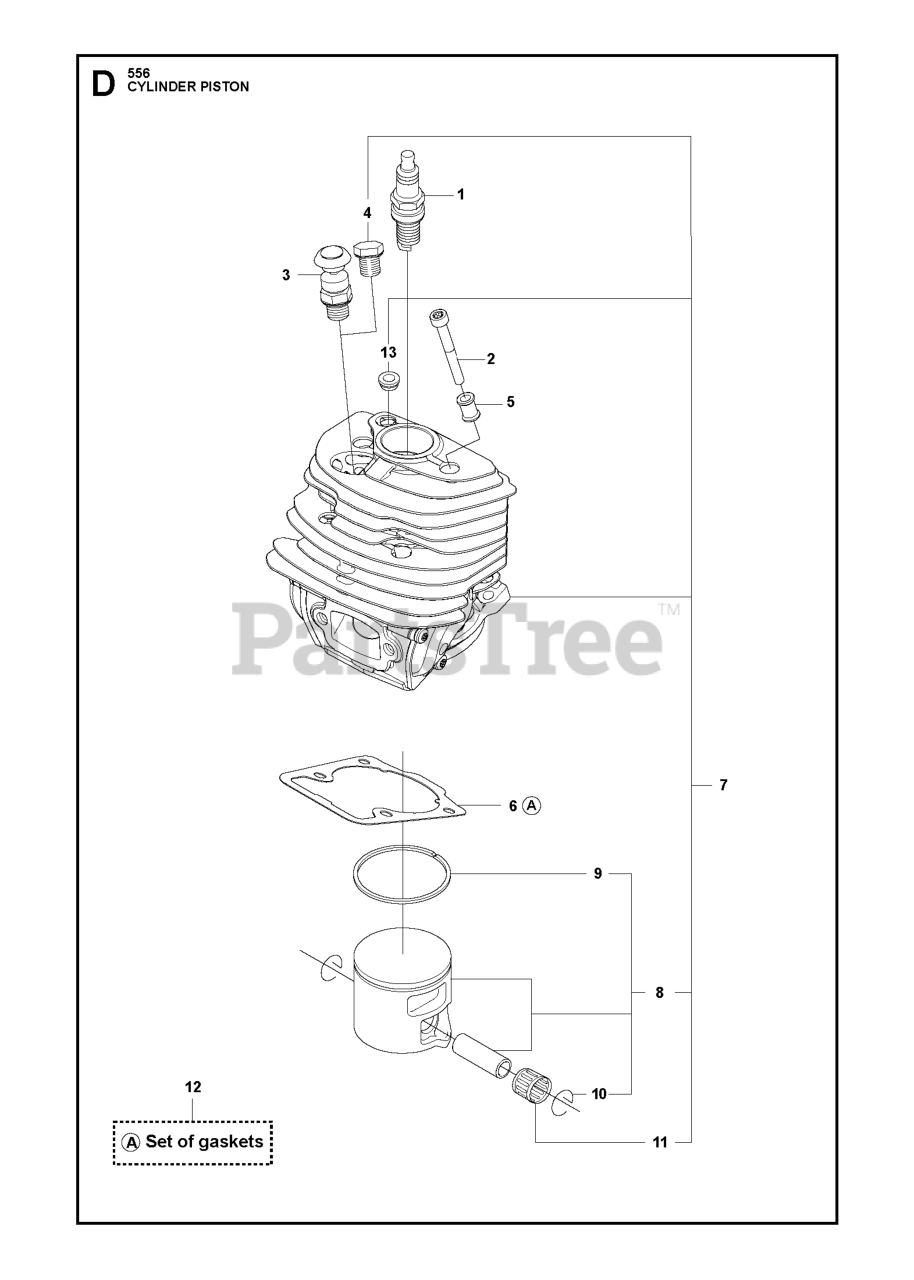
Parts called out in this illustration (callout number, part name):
2	VALVE STEM LT
3	RIM ASM 6" FRONT SILVER
4	TUBE.5.3/4.5/6
5	TIRE HEAVY DUTY
6	FITTING LT
7	BEARING T
8	CAP, AXLE BLK
9	TIRE.18X9.5-8 TURF SAVER
10	TUBE
11	RIM ASM 8" REAR SILVER
